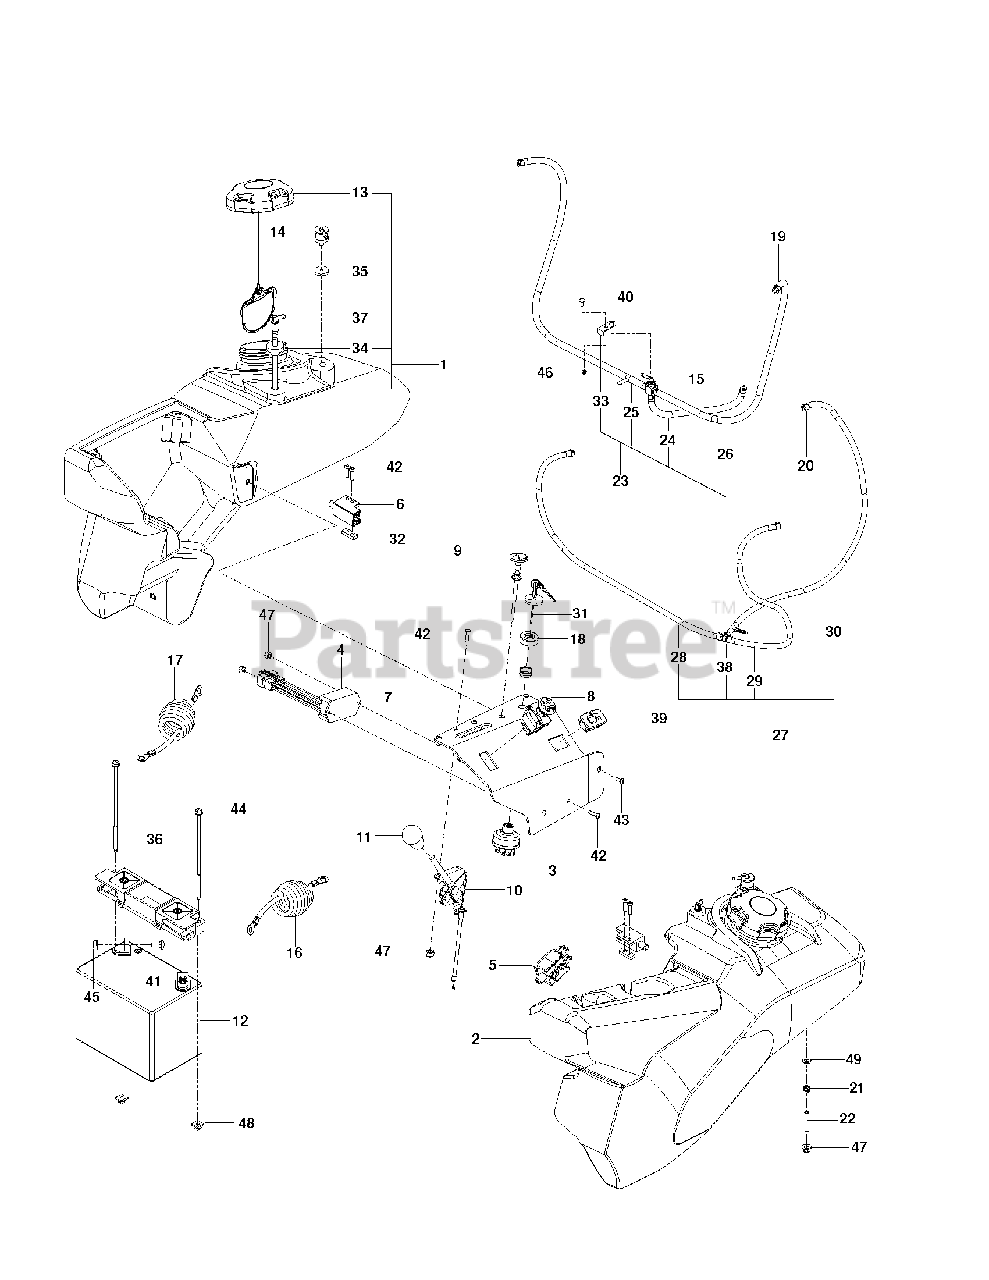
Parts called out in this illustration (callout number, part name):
3	PANEL, CONTROL GAS BLACK
4	TIMER, SEAT
5	SWITCH, BRAKE 3P
7	SWITCH, IGNITION, INDAK
8	SWITCH, PTO 10 AMP
9	CABLE, CHOKE, 38
10	CABLE, THROTTLE, 38
11	KNOB - SHIFT
13	CAP, FUEL
14	VALVE.FUEL.CHECK
15	FUEL VALVE
16	POST.CABLE LONG
17	NEG. CABLE, 28"
19	HOSE CLAMP
20	CLAMP, HOSE
22	STUD, 5/16C
24	FUEL LINE 5"
26	FUEL LINE 24"
28	FUEL LINE 33"
31	KEY, IGNITION
32	TAPPED PLATE
33	BRACKET FUEL VALVE
34	RUBBER GROMMET
35	GROMMET, CHECK VALVE
36	BATTERY HOLD DOWN
39	HOUR METER
40	HCS 1/4C X 3/4 HCS
41	BOLT 5/16C X 3/4" CARRIAGE
42	SCR #10-24 X .75 SKT HD BLK
43	SCR #10-24 X 3/8 SKT HD BLK OX
44	BOLT - 1/4-20 X 7.5
45	5/16-18 NYLOC FLANGE NUT
46	JAM NUT 1/4C
47	NUT 10-24 NYLOC
48	PUSH NUT-NYLON
49	FLAT WASHER 5/16 SAE
